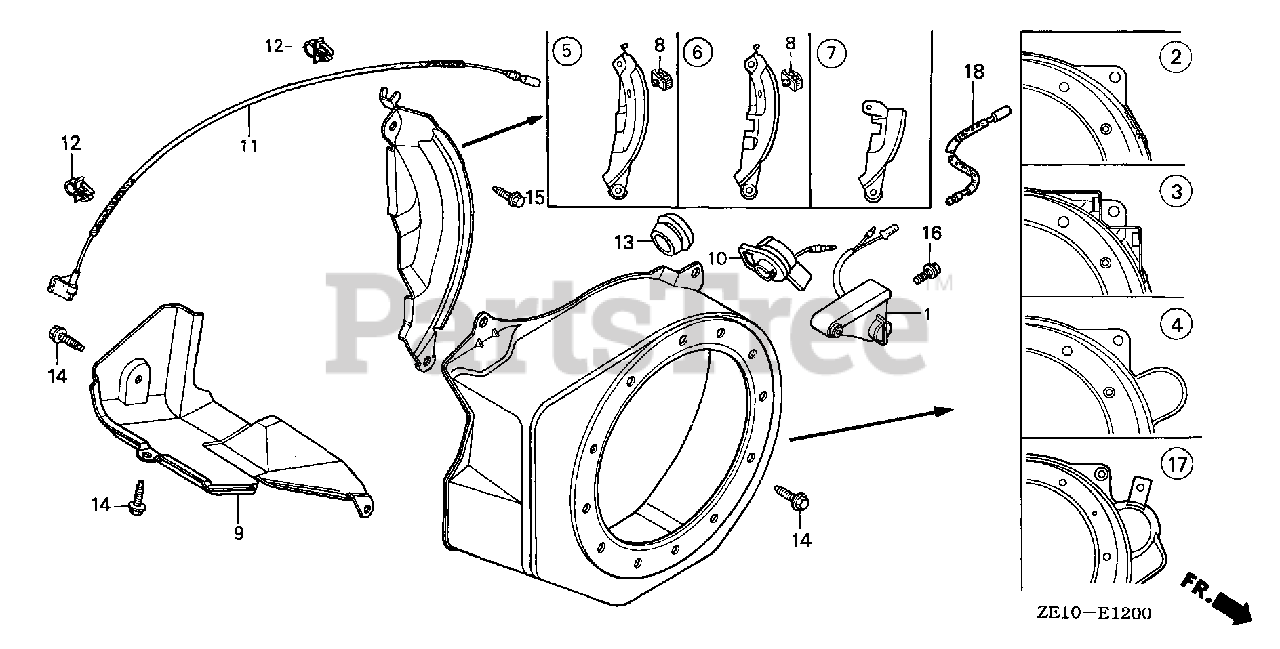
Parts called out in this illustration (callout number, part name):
2	COVER, FAN *R280*
5	PLATE, SIDE (STD) Use up to Engine SN 3172661.
5	PLATE, SIDE (STD)
9	SHROUD
10	SWITCH ASSY., ENGINE STOP
11	WIRE, STOP SWITCH (395MM)
11	WIRE, STOP SWITCH (370MM)
12	HOLDER, STOP SWITCH WIRE
14	BOLT, FLANGE (6X12) (CT200)
15	BOLT, FLANGE (6X20) (CT200)
